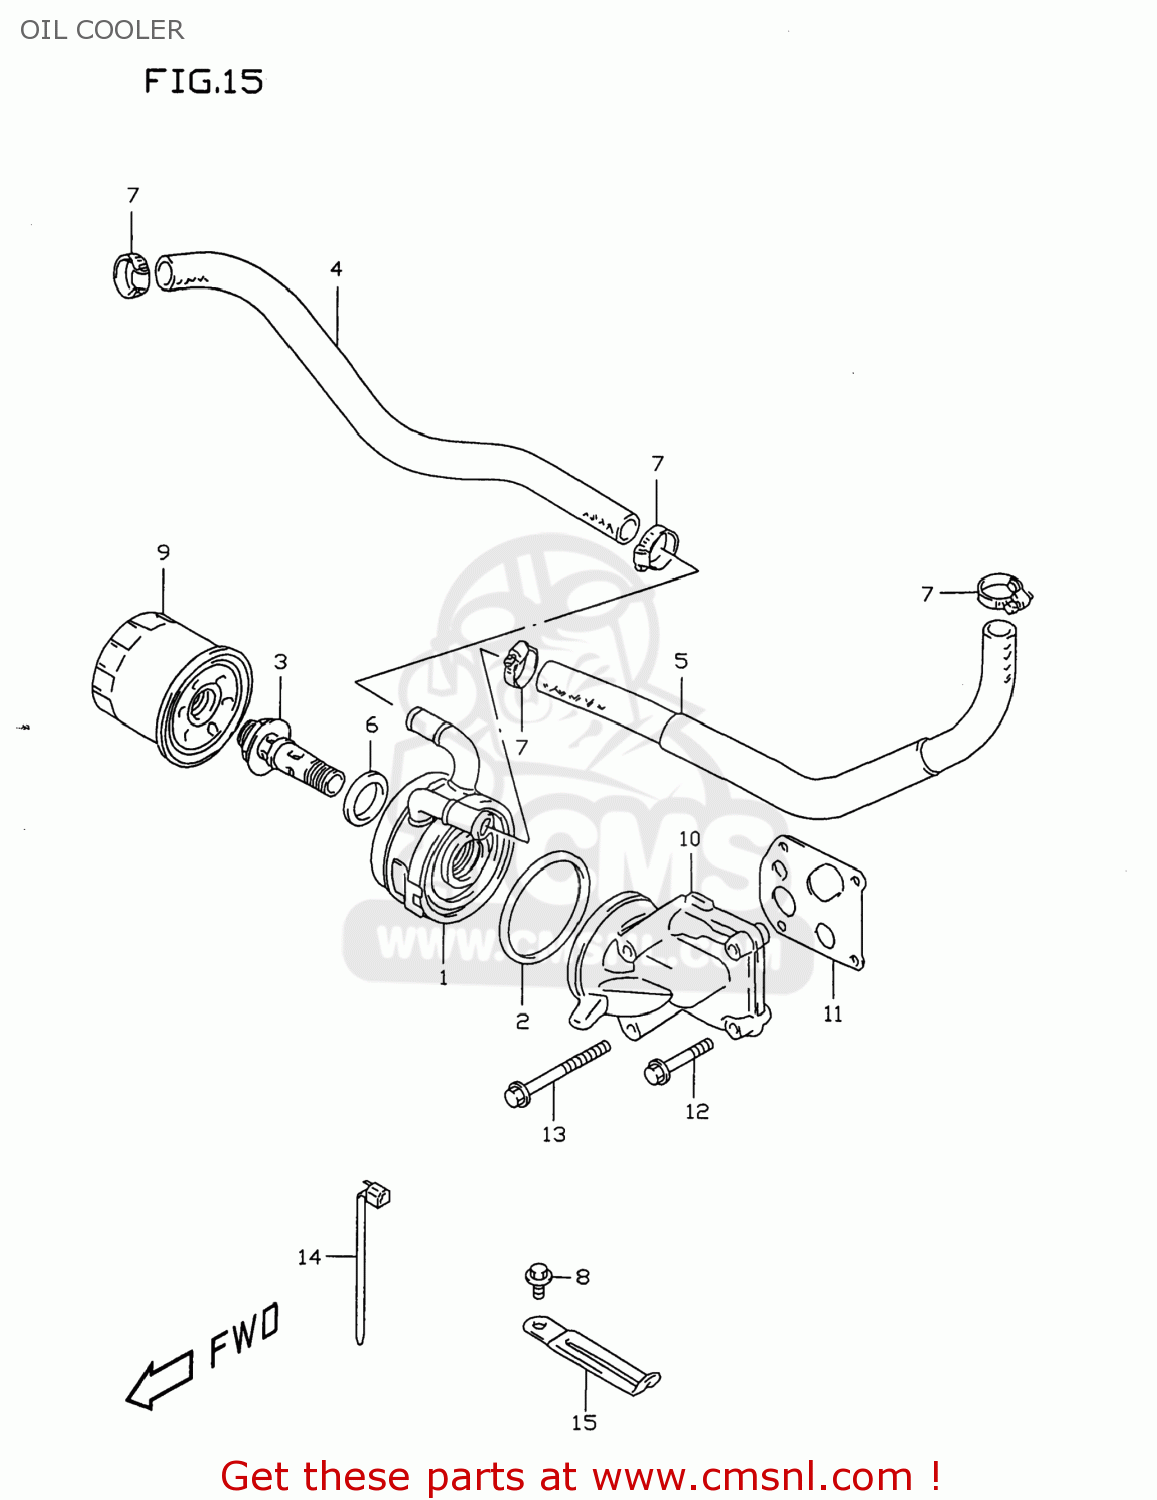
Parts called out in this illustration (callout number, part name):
1	COOLER ASSY,OIL
2	O RING(D:3.1,ID:63.9)
3	BOLT,OIL COOLER UNION
4	HOSE,OIL COOLER WATER OUT
5	HOSE,OIL COOLER WATER IN
6	SHIM
7	CLAMP
8	BOLT 6X12
9	FILTER ASSEMBLY,ENGINE OIL
10	HOLDER,OIL FILTER
11	GASKET,OIL FILTER HOLDER
12	BOLT(6X40)
13	BOLT(6X65)
14	CLAMP(L:235)
15	CLAMP(L:80)
